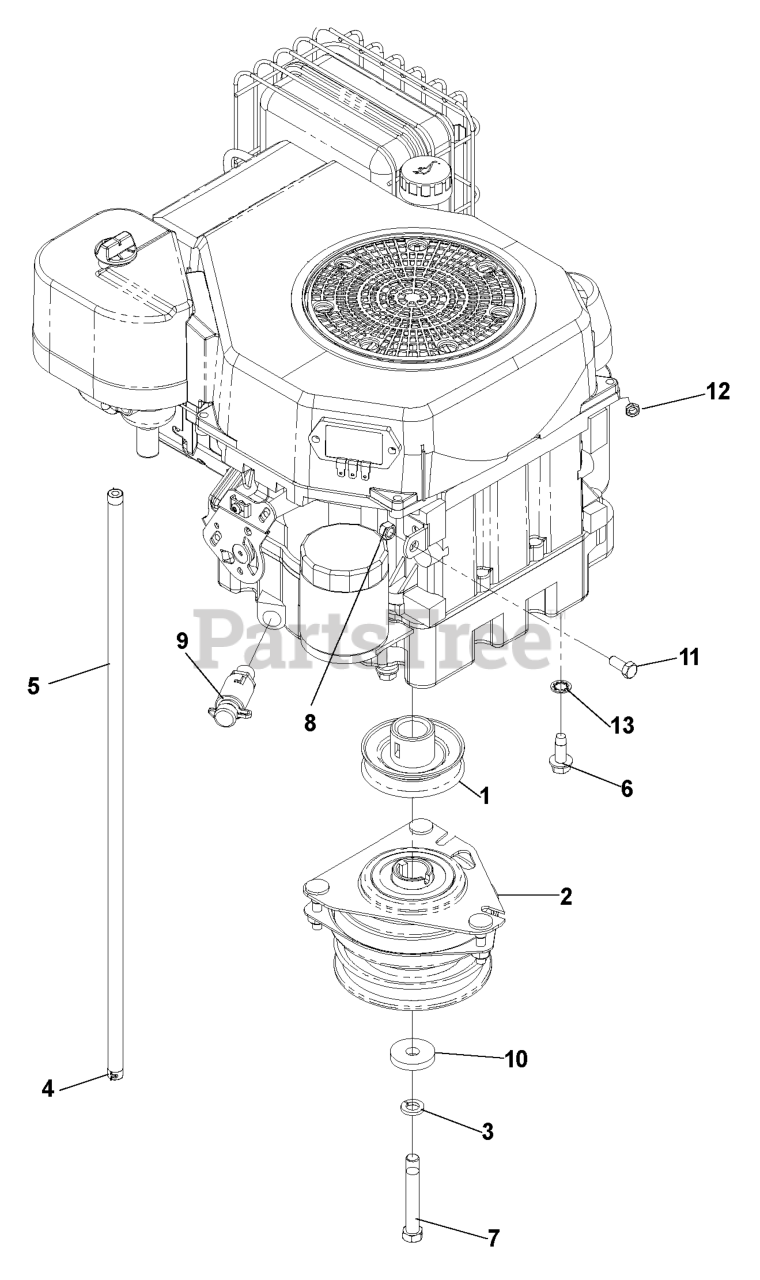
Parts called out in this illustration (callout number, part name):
2	CLUTCH 90 FT/LB OGURA
3	WASHER 7/16 LOCK
4	HOSE CLAMP
5	FUEL LINE 24"
6	BOLT 3/8-16 X 1.0
7	HEX SCREW 7/16-20 X 3
8	NUT 5/16 NYLOC
9	OIL DRAIN FITTING
10	CLUTCH, WASHER
11	SCREW 5/16C X 1 HEX CAP
12	JAM NUT 1/4C (2 2 PW01)
13	WASHER
